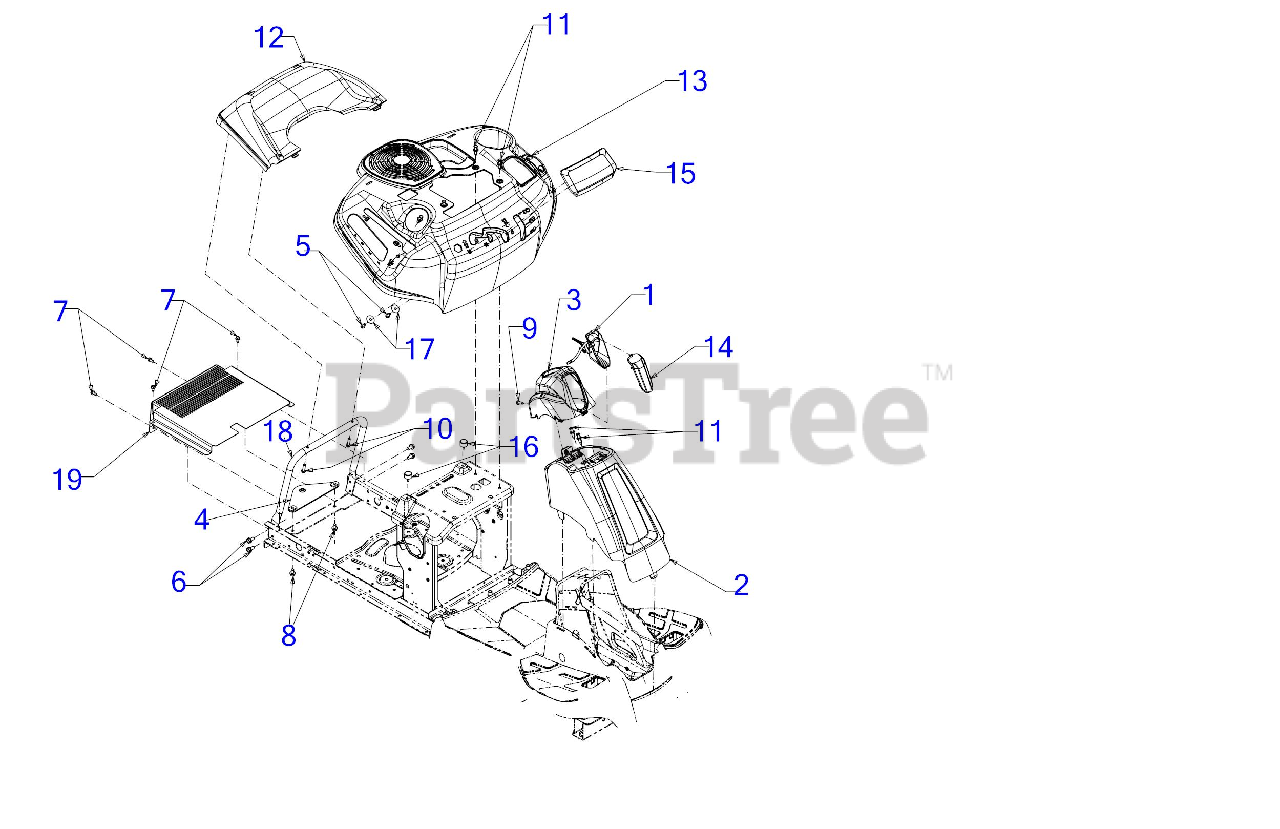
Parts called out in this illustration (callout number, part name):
1	HEADLIGHT HARNESS ASSEMBLY
2	COLUMN COVER ASSEMBLY (MTD RED)
3	STEERING COLUMN CAP (MTD RED)
5	HEX SCREW 1/4-15 x .50
6	SCREW 5/16-18 x .750
7	SCREW 1/4-20 X.500
8	SCREW 5/16-18 x .625
9	SCREW 1/4-20X.75
10	SCREW 1/4-15 x 1.00
11	PLASTIC RIVET
13	FENDER
14	LED HEADLIGHT LENS
15	FENDER COVER
16	BUMPER .62 DIA x .50
17	FLAT WASHER
19	HYDRO COVER HEAT SHIELD (B&S)
